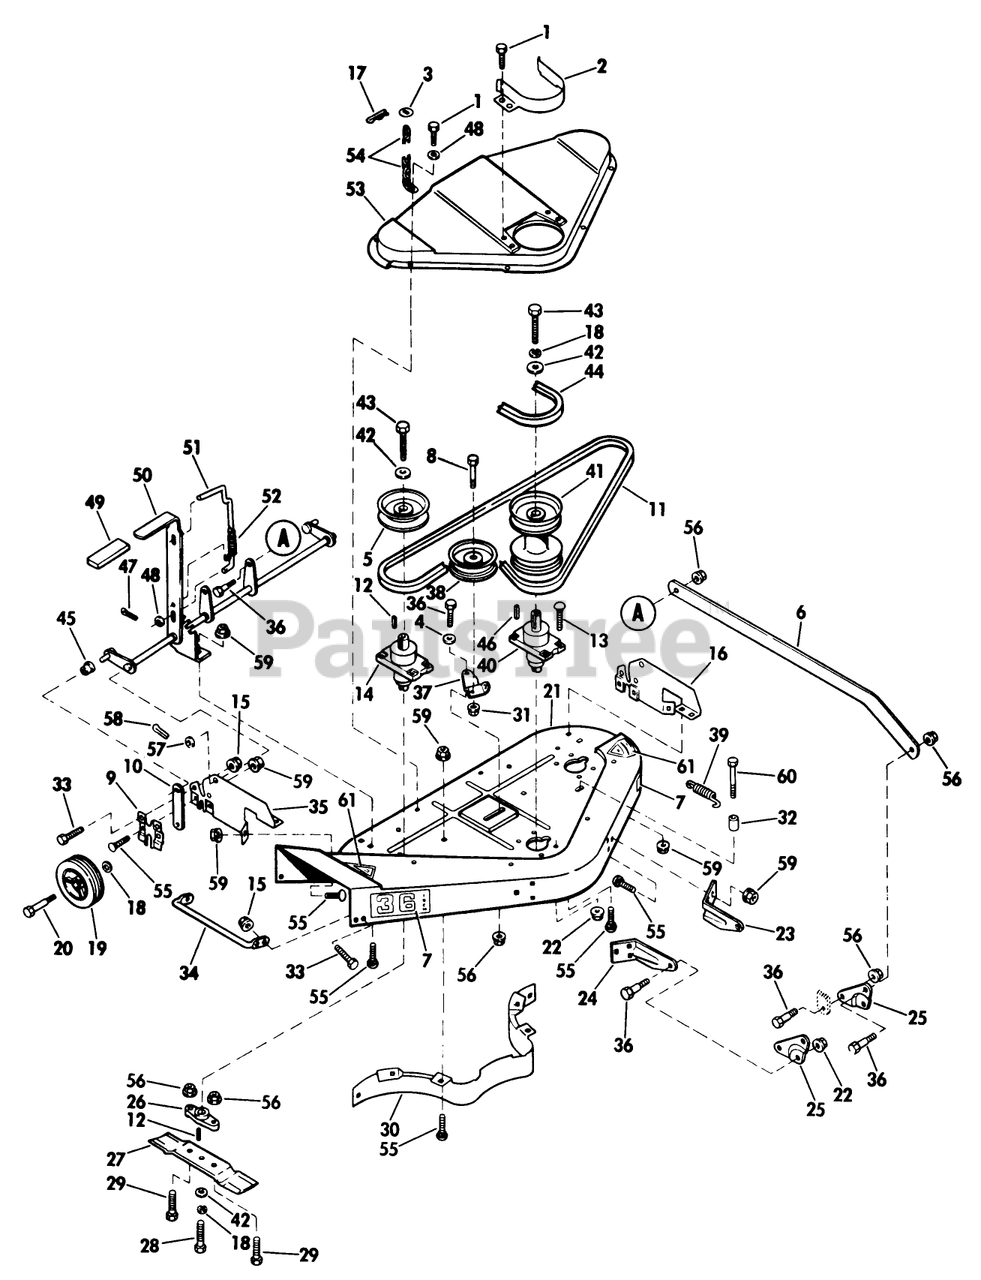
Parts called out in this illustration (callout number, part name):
1	Screw-Belt Cover
9	Retainer-Height Adj. Slide
10	Slide-Height Adjuster
12	Key-Bld-Spindle
15	STOP NUT
16	Bracket-Wheel Mounting L.H.
19	Wheel Tire Assembly
22	Locknut-Large Flange
25	Pivot-Blade Housing
26	Adapter-Blade
28	Screw-Blade
29	Screw-Blade
30	Baffle-Housing
35	Bracket-Wheel R.H.
37	Lever-Idler
38	Pulley-Idler
39	Spring-Idler Lever
43	Screw-Nylok
45	Bushing-Height Adjuster
49	Grip-Handle
50	Shaft Assembly
51	Latch-Slide
52	Spring-Latch
57	Washer-Height Adjuster
